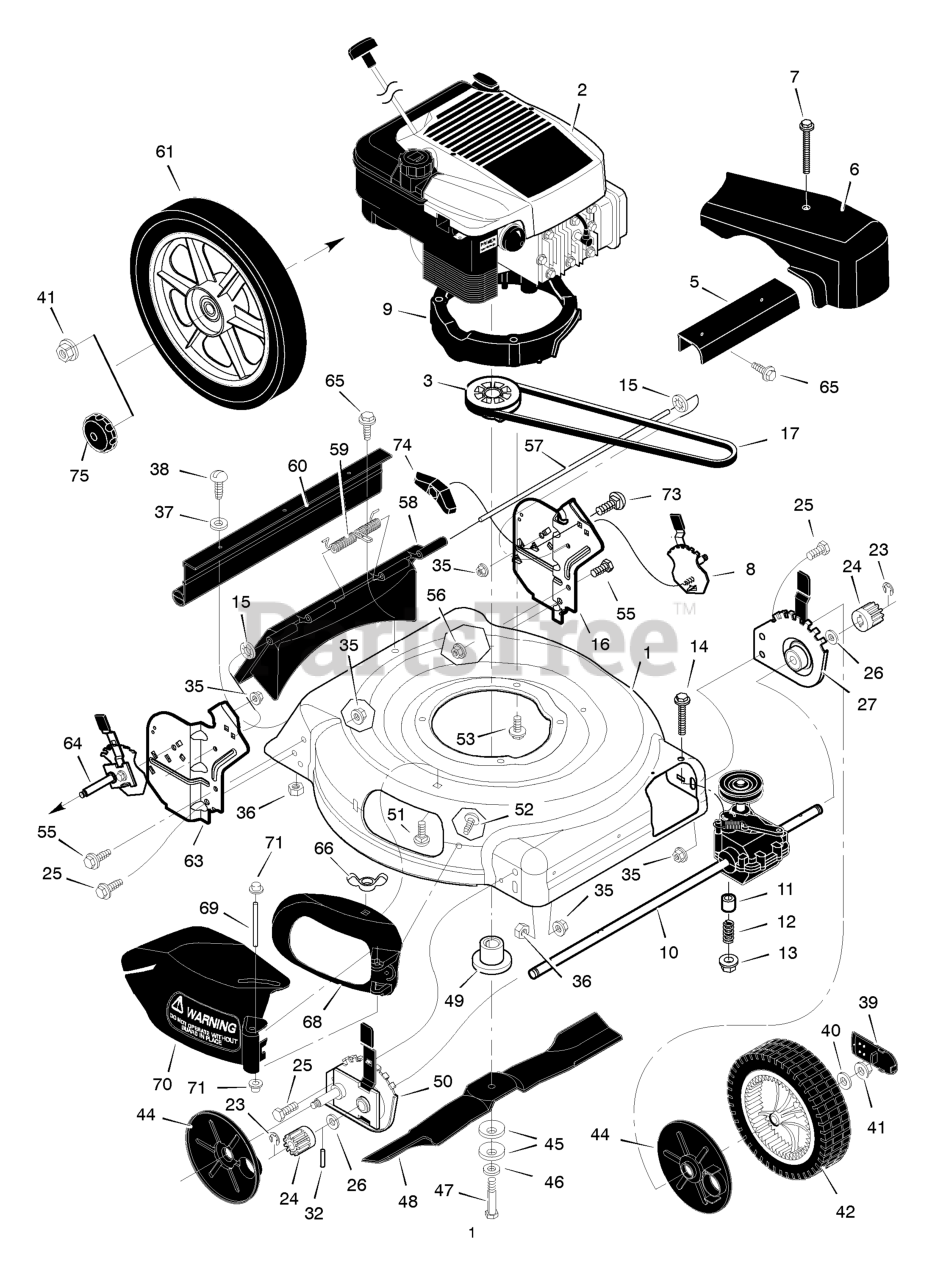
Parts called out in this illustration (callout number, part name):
1	Housing
2	Engine *
3	Pulley, Crankshaft
4	Pin, Spring
5	Cover, Axle (Black)
6	Cover, Belt (Black)
8	Adjuster, Left Height
9	Spacer, Engine
10	Transmission *
13	Nut
14	Bolt
15	Retainer, Push
16	Bracket, Left Handle
24	Gear, Pinion
25	Bolt
27	Adjuster, Left Frt. Height
32	Pin, Drive
35	Nut, Flange
36	Nut, Hex
39	Cap, Hub
40	Washer
41	Nut, Flange
42	Wheel, Drive
44	Cover, Dust
45	Washer, Belleville
49	Adapter, Blade
50	Adjuster, Right Frt. Height
51	Bolt, Carriage
53	Bolt, Engine
55	Bolt
56	Nut, Flange
57	Rod, Pivot
58	Door, Rear (Gray)
59	Spring
60	Deflector, Rear
61	Wheel, Rear
63	Bracket, Right Handle
64	Adjuster, Right Height
66	Wingnut
69	Pin, Pivot
70	Deflector, Chute (Black)
71	Cap, Push
73	Bolt, Carriage
